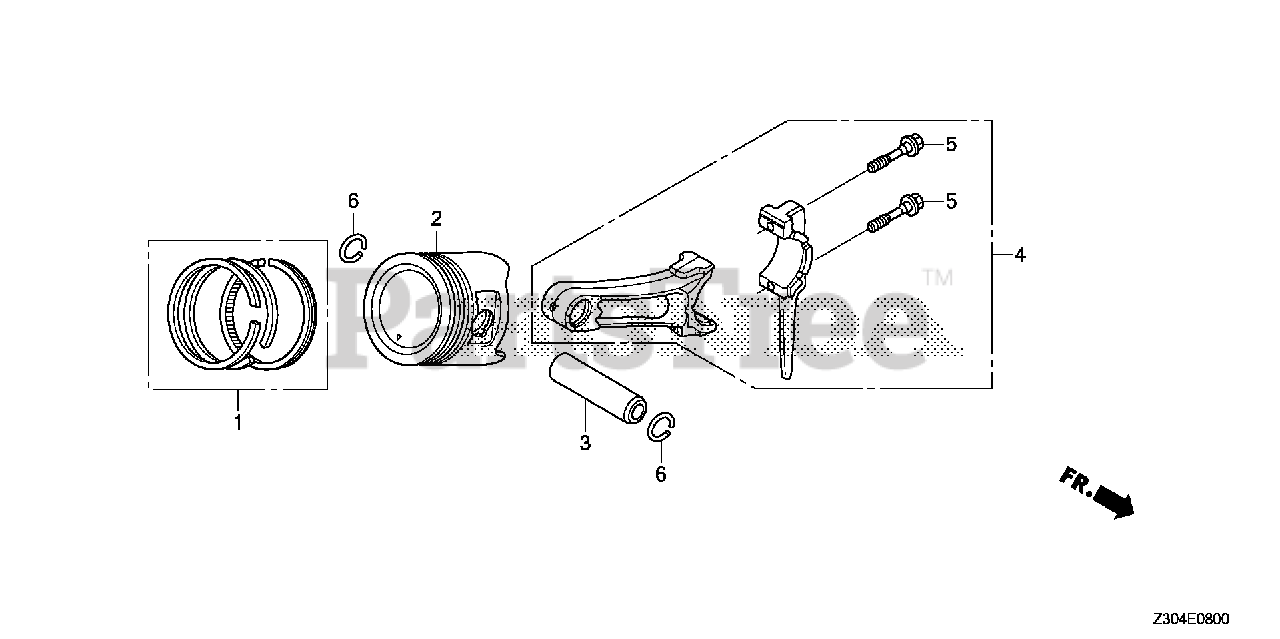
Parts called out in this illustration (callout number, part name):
1	RING SET, PISTON (STD) (TEIKOKU)
1	RING SET, PISTON (0.25) (TEIKOKU)
1	RING SET, PISTON (0.50) (TEIKOKU)
1	RING SET, PISTON (0.75) (TEIKOKU)
2	PISTON (STD)
2	PISTON (0.25)
2	PISTON (0.50)
2	PISTON (0.75)
3	PIN, PISTON
4	ROD ASSY., CONNECTING (0.25 LOWER SIZE)
4	ROD ASSY., CONNECTING (STD)
5	BOLT, CONNECTING ROD
6	CLIP, PISTON PIN (20MM)
